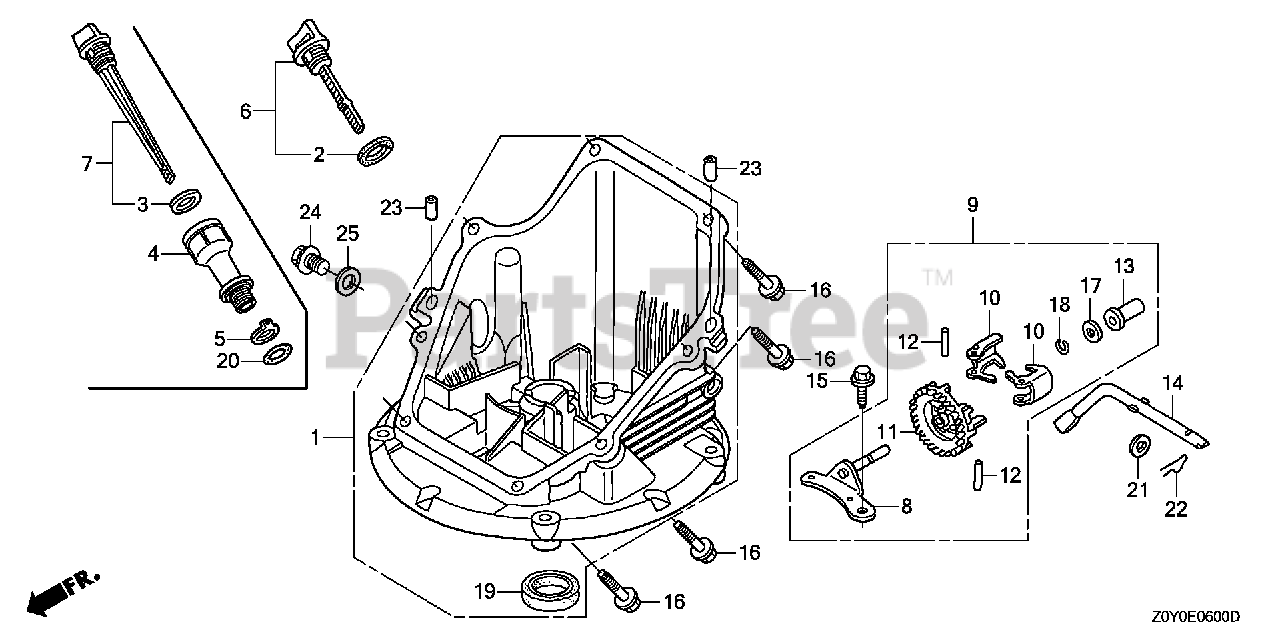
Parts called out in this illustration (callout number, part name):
1	PAN ASSY., OIL (SAE)
2	GASKET, OIL FILLER CAP (NOT AVAILABLE)
6	GAUGE ASSY., OIL LEVEL
8	SHAFT, GOVERNOR HOLDER
9	GOVERNOR ASSY.
10	WEIGHT, GOVERNOR
11	HOLDER, GOVERNOR WEIGHT
12	PIN, GOVERNOR WEIGHT
13	SLIDER, GOVERNOR
14	SHAFT, GOVERNOR ARM
15	BOLT, FLANGE (6X14)
16	BOLT, FLANGE (6X25) Use up to Engine SN 2056819.
17	WASHER, THRUST (6MM)
18	CLIP, GOVERNOR HOLDER
19	OIL SEAL (28X41.25X6)
21	WASHER, PLAIN (6MM)
22	PIN, LOCK (8MM)
23	PIN, DOWEL (8X20)
24	BOLT, DRAIN PLUG
25	WASHER, DRAIN PLUG (12MM)
